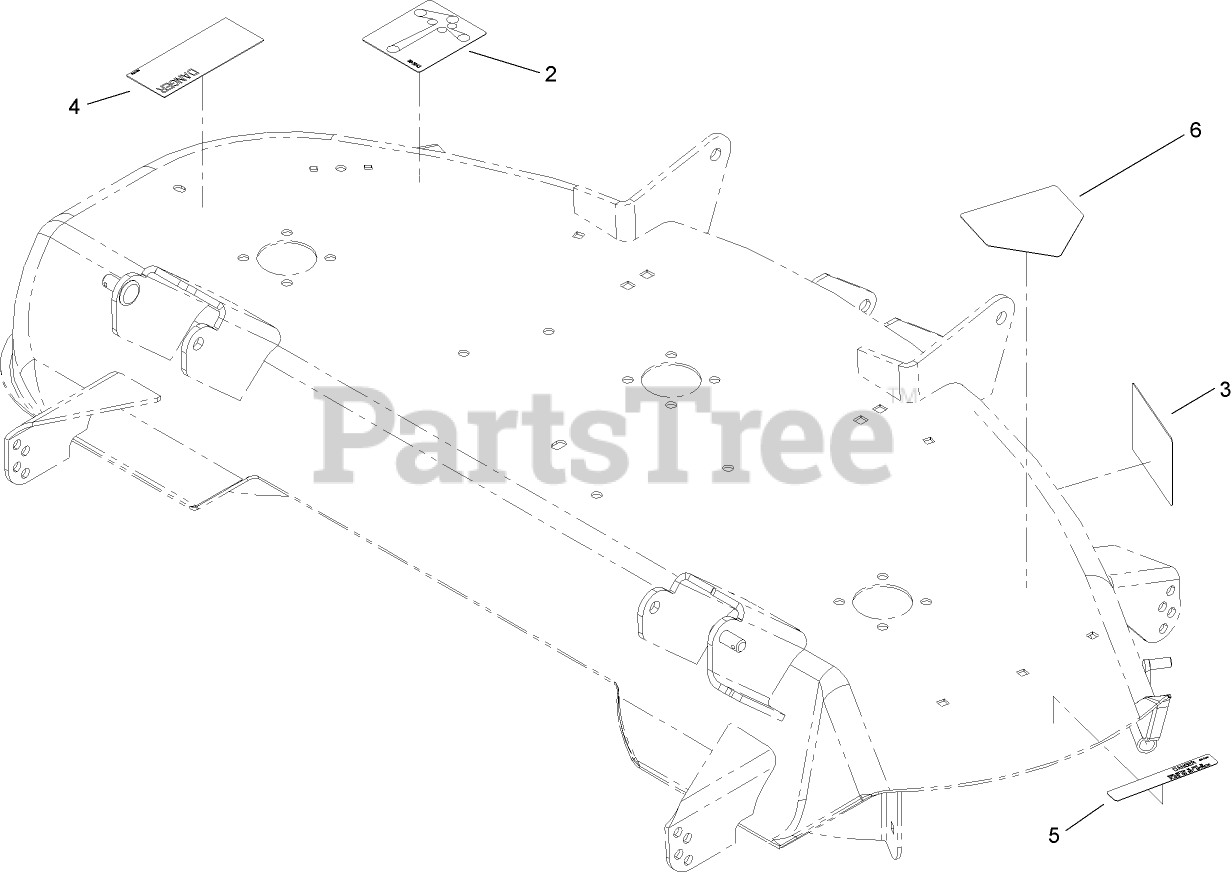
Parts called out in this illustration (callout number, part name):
2	DECAL-ROUTING, BELT
3	DECAL-WHEEL, GAGE
4	DECAL-DANGER
5	DECAL-CAUTION
6	DECAL-DANGER
